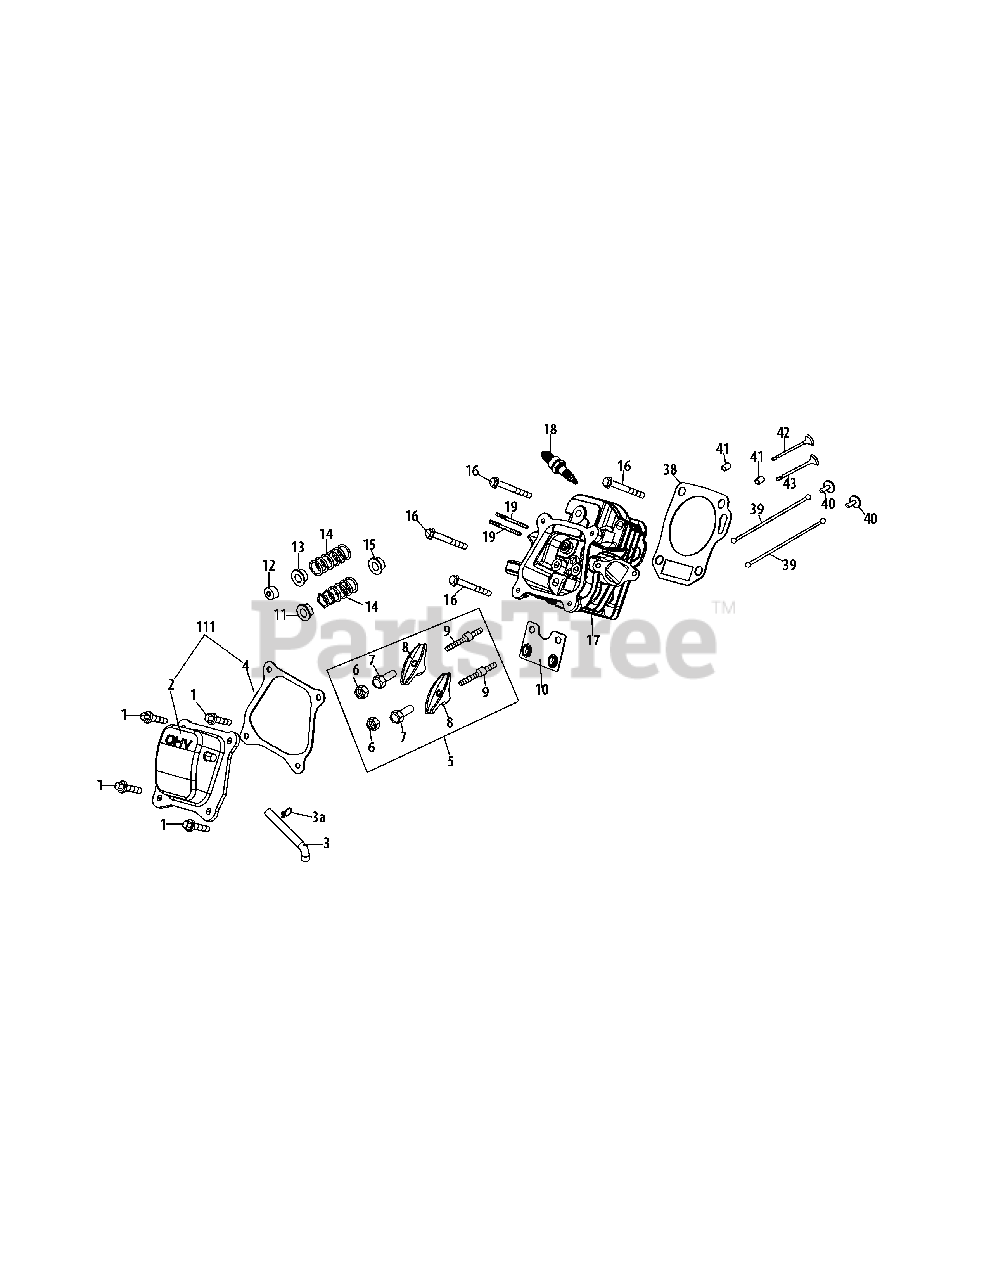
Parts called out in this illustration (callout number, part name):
1	Bolt M6×16
2	Valve Cover
4	Valve Cover Gasket
5	Roker Arm Assembly
6	Nut, Pivot Locking
7	Adjusting Nut, Valve
8	Rocker Arm
9	Bolt, Pivot
10	Push Rod Guide
11	Retainer, In. Valve Spring
12	Adjuster, Ex. Valve
13	Retainer, Ex. Valve Spring
14	Valve Spring
15	Intake Valve Seal
16	Bolt M8×55
17	Cylinder Head Assembly
18	Spark Plug
19	Stud M8×36
19	Muffler Stud Assembly
38	Gasket Cylinder Head
41	Dowel Pin, 10×16
42	Exhaust Valve
43	Intake Valve
111	Valve Cover Kit
